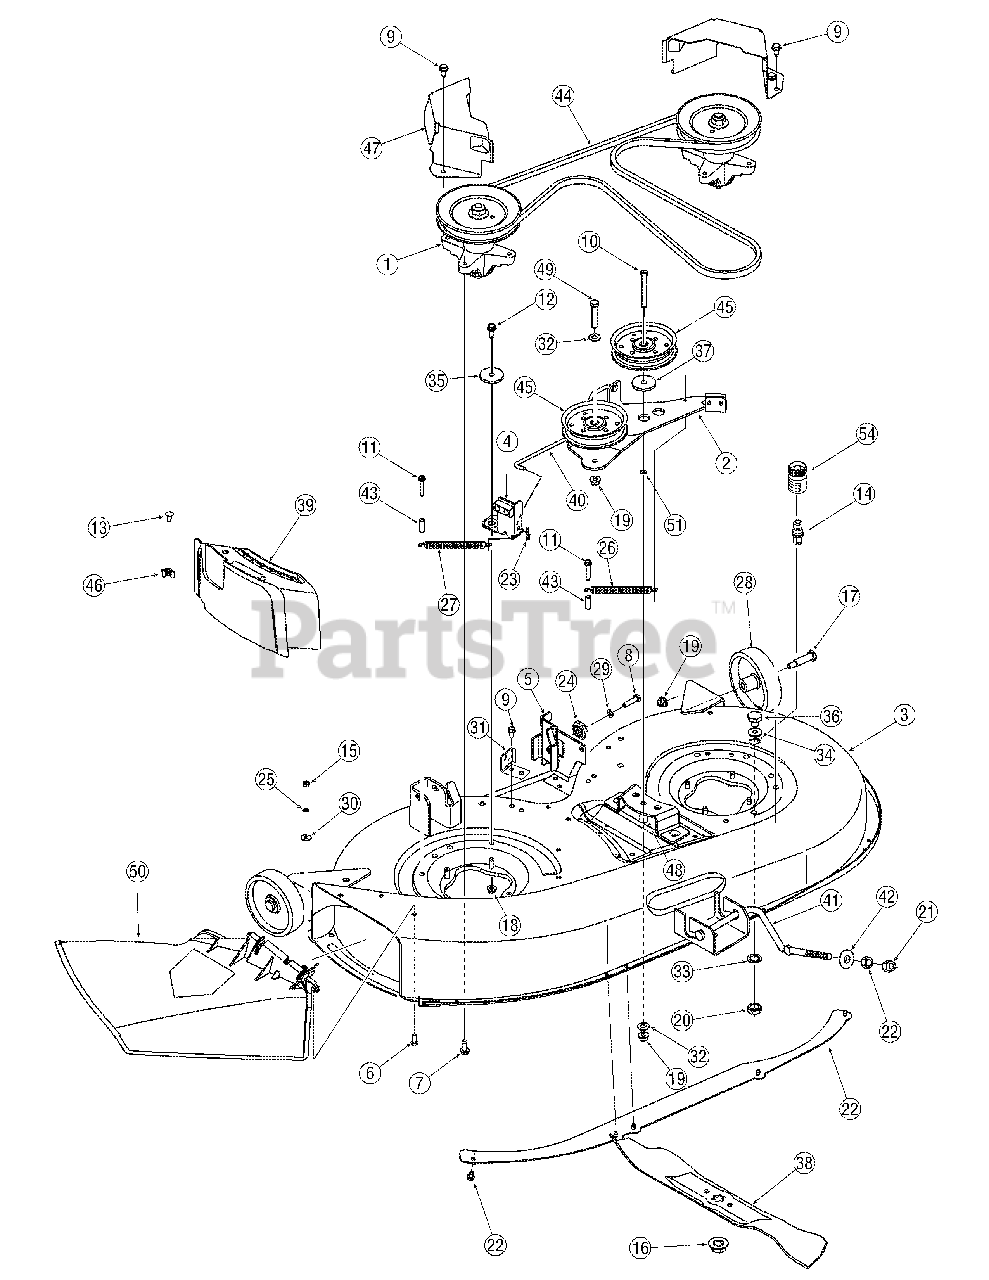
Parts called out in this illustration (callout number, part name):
1	Spindle Assembly, Pul, 6.3" Dia
3	Deck Shell, 42" (w/o Wheel Brkt)
6	Screw, 1/4-20, .75, Gr5
7	Screw, 5/16-18, 0.750
8	Screw, 5/16-18, 1.250
9	Screw, 5/16-18, 0.625
10	Screw, 3/8-16, 3.50, Gr5
11	Screw, 1/4-20, 1.500
12	Screw, 5/16-18, .75, Gr5
13	Carriage Screw, , 1/4-20 x .62
14	Deck Water Nozzle
15	Nut, Hex, 1/4-20, Gr5
16	Nut, Flange, 5/8-18
17	Screw, Shldr, .498 x 1.53, 3/8-16
18	Nut, Flange Lock, 5/16-18, GrF
19	Nut, Flange Lock, 3/8-16, GrF
20	Nut, Hex, M16-1.5
21	Nut, Hex Lock, 1/2-13, Gr8
22	Nut, Hex, 1/2-13, Gr5
23	Pin, Cot, .072 Dia. x 1.13 Lg
24	Gear, Deck Adjustment
25	Nut, Push, .25 ID x .50 OD
26	Spring, Exten. , .75 Dia. x 6.375
27	Spring, Exten. , .50 Dia. x 6.375
28	Wheel, Deck 5.0 x 1.38
29	Washer, Lock, 5/16
30	Washer, Bell, .265 x.75 x .062
32	Washer, Flat, .385 x .87 x .06
33	Washer, Lock, 5/8, Internal Tooth
34	Washer, Flat, .64 x 1.24 x .06
35	Spacer, Shoulder, .5000 x .1475
36	Plug, Screw, M16 x 1.5
37	Spacer, Shoulder, .8840 x .190
38	Blade, 21.23", Star 3-in-1
39	Mulch Plug
40	Control Rod, Brake
41	Deck Rod, Front Adjustable
42	Pivot Cup, Deck Lift
43	Spacer, .260 x .372 x 1.030
44	Belt, V-Type
45	Idler Pulley, 4.25" Dia.
46	Wing Nut, 1/4-20
48	Spacr, 3/8 ID x .68 OD x 1.46 Lg.
49	Screw, 3/8-16 x 1.75
50	Chute Assembly, Discharge
51	Nut, Push, 3/8
52	Screw, 1/4-20, 0.500
54	Water Nozzle Adapt
